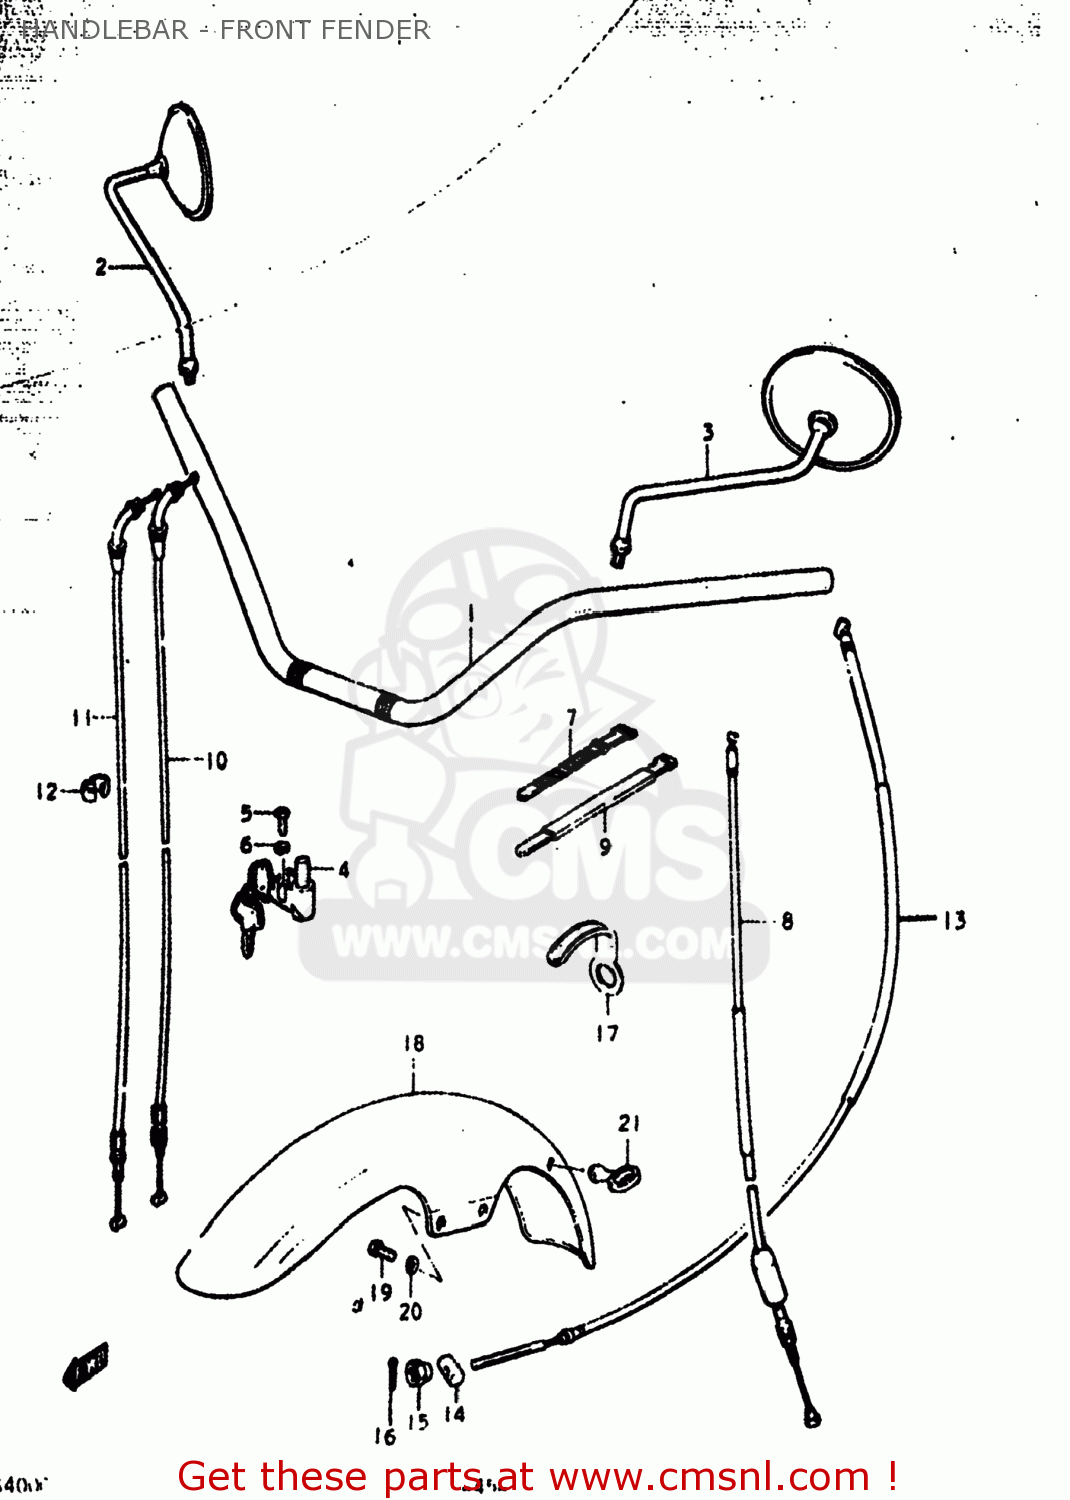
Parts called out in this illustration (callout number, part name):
1	HANDLEBAR,RIGHT
2	MIRROR ASSEMBLY,RIGHT
3	MIRROR ASSEMBLY,LEFT
4	LOCK ASSEMBLY,STEERING
5	SCREW
6	LOCK WASHER
7	CLAMP(L:120)
8	CABLE ASSEMBLY,CLUTCH
9	CLAMP
10	CABLE ASSEMBLY,THROTTLE
11	CABLE ASSEMBLY,THROTTLE
12	CLIP
13	CABLE,FRONT BRAKE
14	PIN
15	NUT
16	PIN
17	LAMP ASSEMBLY
18	FENDER,FRONT
19	BOLT
20	LOCK WASHER
21	GUIDE,CABLE
